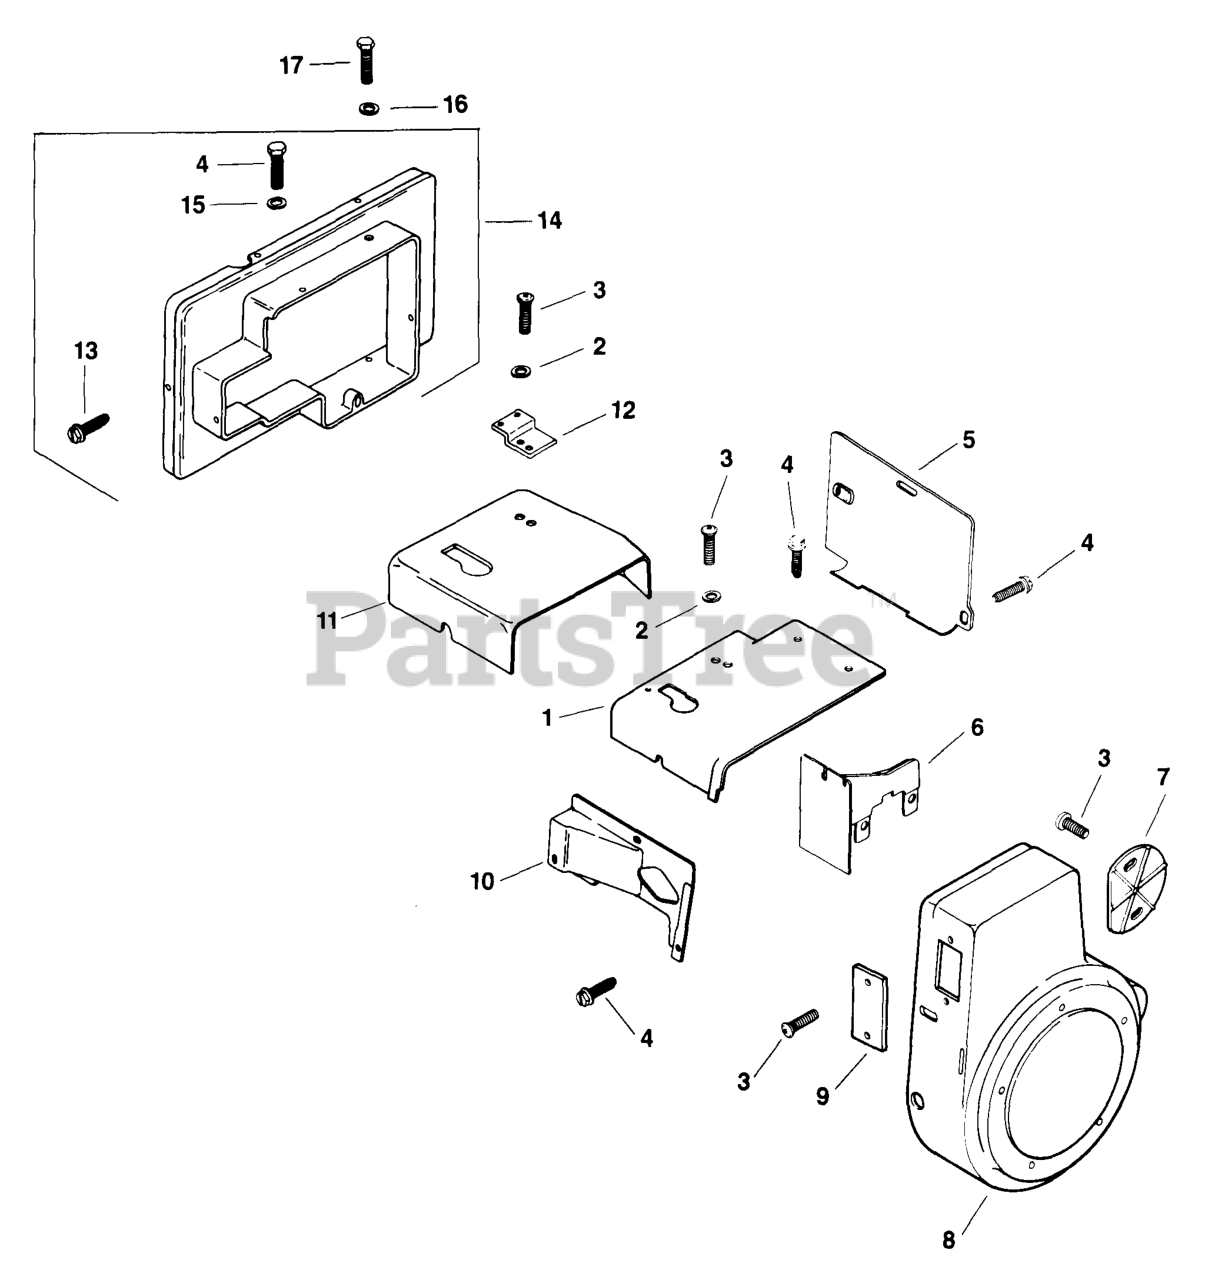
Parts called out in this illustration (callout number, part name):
2	WASHER, FLAT 1/4" (O.D. 5/8")
3	SCREW, POZ TRS HD 1/4-20X5/8" - DISCONTINUED
4	SCREW, WSH HD TAP 1/4-20-5/8" - DISCONTINUED
5	BAFFLE, CYLINDER
6	BAFFLE, INNER - DISCONTINUED
8	KIT, HOUSING
8	HOUSING - USE 47 027 44
10	BAFFLE, SIDE AIR - DISCONTINUED
4711308	DECAL - USE 47 113 22
